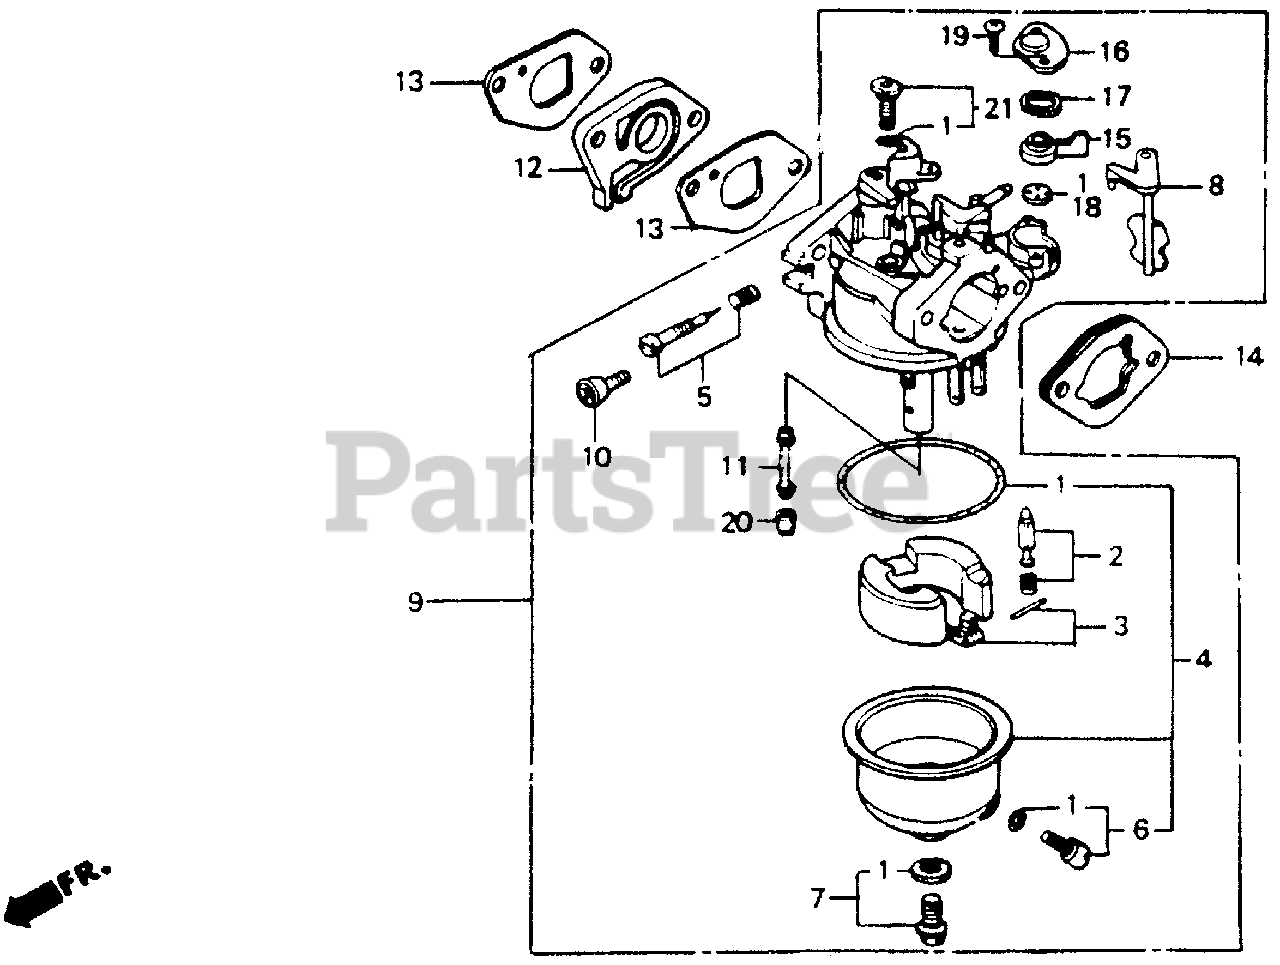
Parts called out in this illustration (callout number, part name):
1	GASKET SET
2	VALVE SET, FLOAT
4	CHAMBER SET, FLOAT
5	SCREW SET, PILOT
6	SCREW SET, DRAIN
7	SCREW SET B
8	CHOKE SET
9	CARBURETOR ASSY. (BE56A A)
9	CARBURETOR ASSY. (BE03A D)
9	CARBURETOR ASSY. (BE03A D/F)
9	CARBURETOR ASSY. (BE03A G)
9	CARBURETOR ASSY. (BE03A H)
10	SCREW, THROTTLE STOP
11	NOZZLE, MAIN
12	INSULATOR, CARBURETOR
13	GASKET, INSULATOR
14	SPACER, CARBURETOR
15	LEVER, VALVE
16	PLATE, LEVER SETTING
17	SPRING, VALVE LEVER
18	GASKET, VALVE
19	SCREW, PAN (3X8)
20	JET, MAIN (#60)
20	JET, MAIN (#62)
20	JET, MAIN (#65)
21	JET SET, PILOT (#35)
